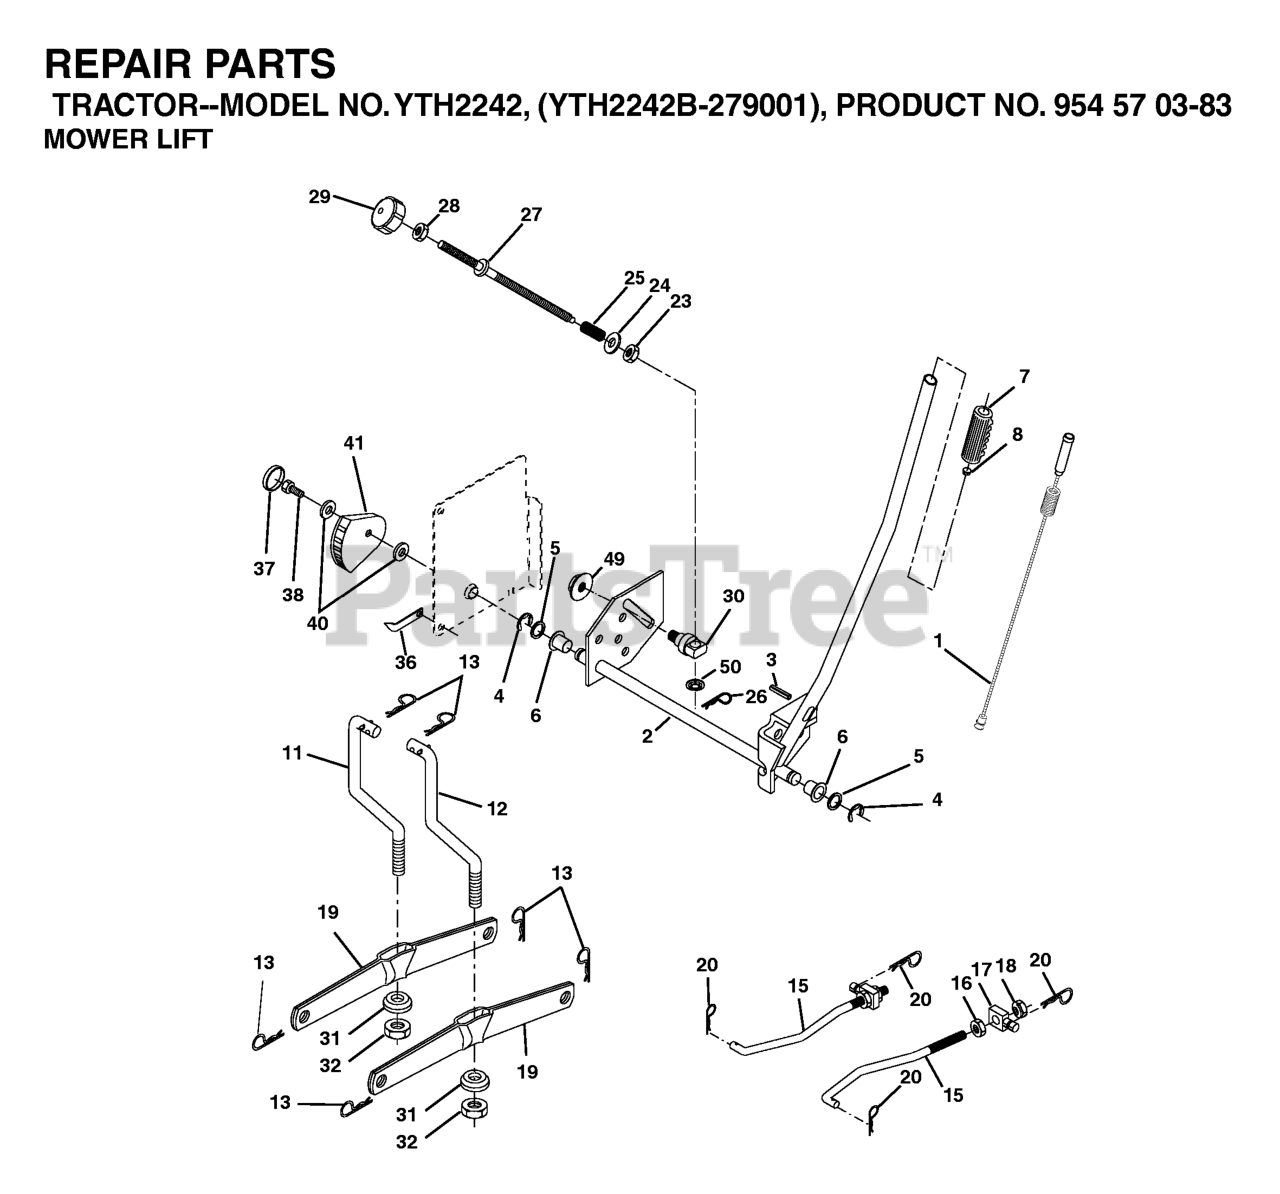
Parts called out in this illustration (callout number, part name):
1	WIRE ASM INNER W/ PLUNGER LT
2	SHAFT ASM R HANDLE
3	PIN GROOVE.
4	RETAINING RING LT
6	BEARING.NYLON
7	GRIP HANDLE
8	PLUNGER BUT KIT
11	LINK LIFT LH
12	LINK LIFT RH
13	RETAINER-SPRNG RB
15	LINK.SUSPENSION.FRONT
16	NUT.HEX.JAM.1/2-13
18	NUT.LK.W/WSH.1/2.
19	ARM.REAR.SUSPENSION
20	SPRING RETAINER
25	SPRING**
26	RETAINER CLIP
27	ROD ADJ LIFT
28	NUT
29	KNOB INF 3/8-16
31	BEARING.PIVOT.LIFT
32	NUT CROWNLOCK 3/8-24
36	POINTER, HEIGHT INDICATOR(2 2)
38	SCREW 5/16-18X1
41	IND. HEIGHT STLT
49	NUT
50	NUT PUSH M
